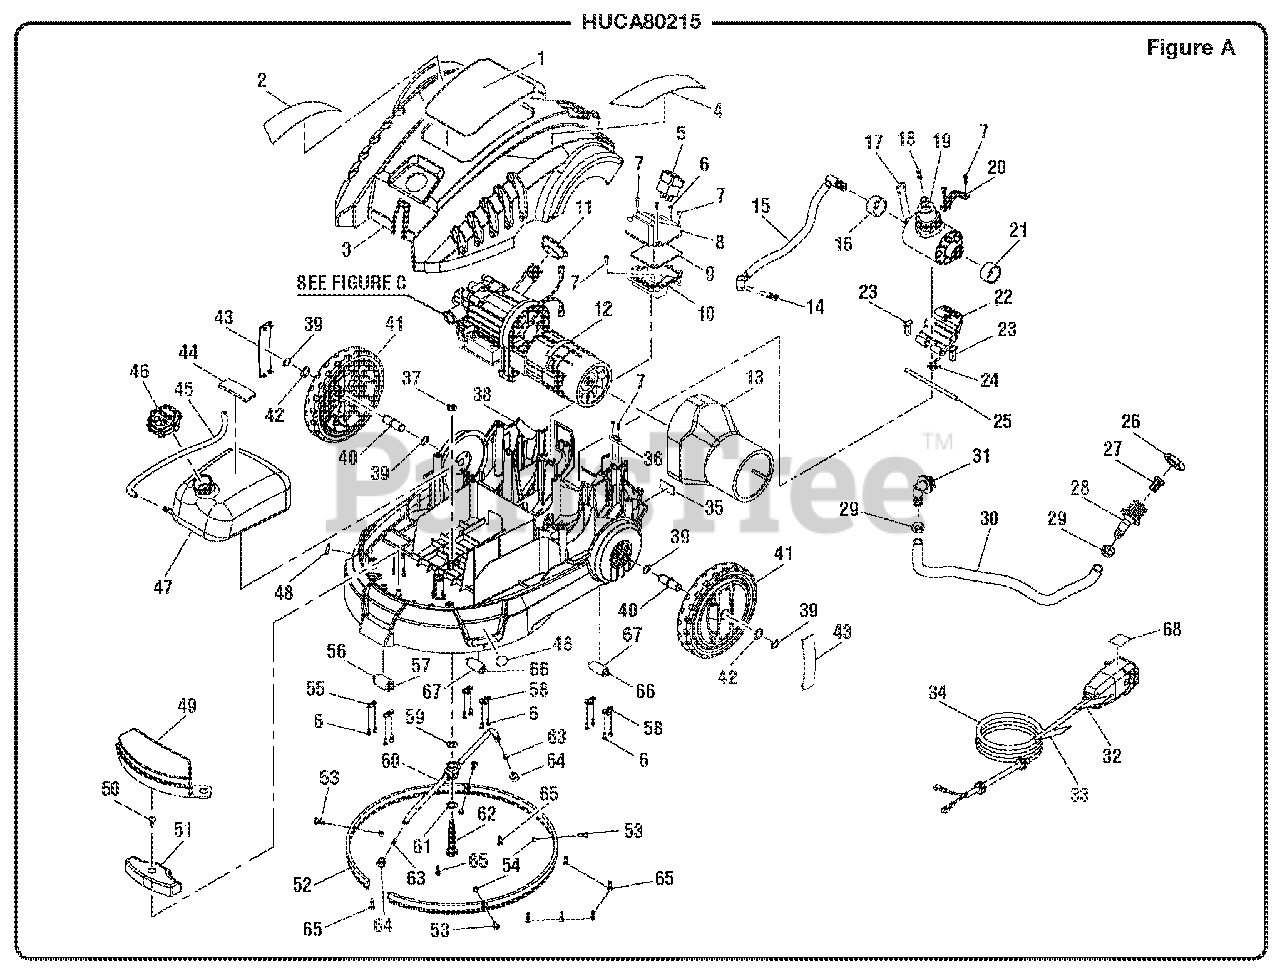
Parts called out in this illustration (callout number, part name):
1	Performance Label
2	Warning Label (French)
3	Top Housing Assembly (Incl. Key Nos. 1-2 & 4)
4	Warning Label (English)
6	Screw (M3.5 x 12 mm)
7	Screw (M4.2 x 15 mm)
8	Switch Box Cover
9	Switch Box Gasket
10	Switch Box
11	Pump Outlet Ring
12	Motor and Pump Assembly
13	Motor Baffle
14	U-pin (2.5 mm)
15	High Pressure Hose Assembly
16	Left Pivot Bushing
17	U-pin (3 mm)
18	Nipple Filter
20	Pivot Clamp
21	Right Pivot Bushing
22	Foot Pedal
23	Bearing Block
24	Torsion Spring
25	Foot Pedal Shaft
26	Inlet Nut
27	Inlet Filter
28	Inlet Connector
29	Hose Clamp
30	Inlet Hose
31	Pump Inlet Connector Assembly
32	Proposition 65 Label (CA)
33	Warning Label
34	Power Cord Assembly (Incl. Key Nos. 32-33)
35	Data Label
36	Cord Clamp
37	Spindle Nut (M10)
38	Lower Housing Assembly (Incl. Key Nos. 35 &48)
39	Retaining Ring
40	Wheel Axle
41	Wheel Assembly
43	Wheel Logo
44	Detergent Tank Pad
45	Detergent Hose
46	Detergent Tank Cap
47	Detergent Tank
48	Foot/Hand Caution Label
49	Lift Handle
50	Screw (M4 × 16 mm)
51	Balast Weight
53	Screw (M4 x 12 mm)
54	Lock Nut (M4)
55	Front Roller Clamp
56	Front Roller Axle
57	Front Roller
58	Rear Roller Clamp
59	Upper Spinner Bushing
60	Spinner Assembly
61	Lower Spinner Bushing
62	Spindle Assembly
63	Spinner Nozzle Assembly
64	Spinner Nozzle Holder
65	Screw (M4.2 X 18 mm)
66	Rear Roller Axle
67	Rear Roller
68	GFCI Label
